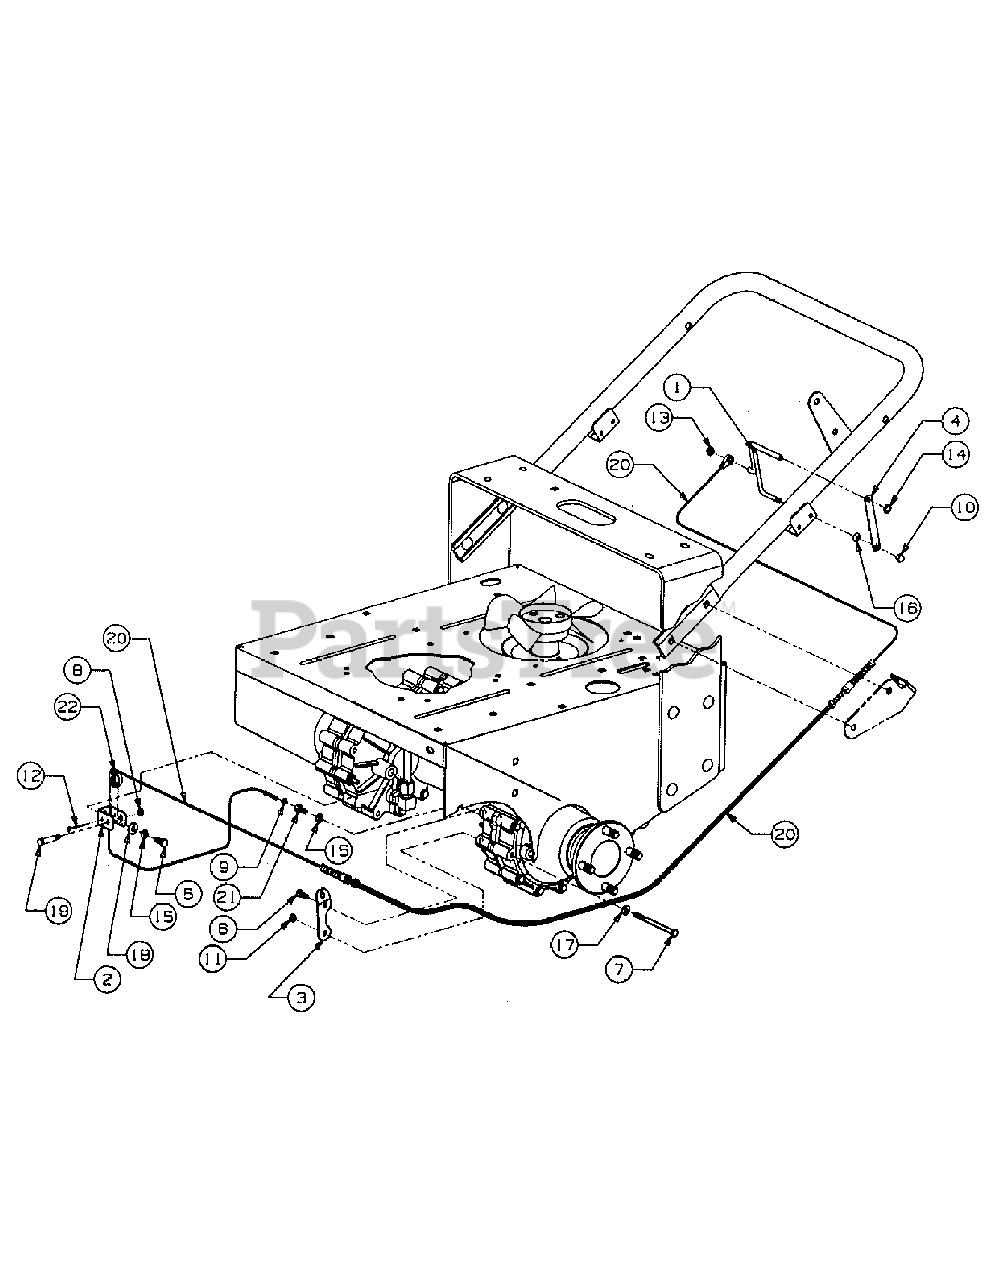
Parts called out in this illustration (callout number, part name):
1	Leverm Drive Wheel Release
2	Bracket, Pulley
3	Plate, Release Cable
4	Plate, Retainer
4	Graphic, Transaxle Release
5	Screw, Hex Cap, 5/16-24 x .75 Gr 5
6	Screw, Hex Wash Hd Tapp, 1/4-20 x .75
7	Screw, Hex Cap, 1/4-20 x 4.0
8	Nut, Hex Top Lock, 1/4-20
9	Nut, Hex #10-32
10	Nut, Hex Lock Stop, 1/4-28
11	Nut, Hex Top Lock, 1/4-20 Gr 5
12	Pin, Cotter, 5/32 Dia x 1.25
13	Nut, Cap Speed, .312 Stud
14	Nut, Push-On Speed, 5/16
15	Washer, Lock 5/16
16	Washer, Spring
17	Washer, Flat .25 x .62
18	Washer, Flat .312 x .750 x .119 Thk
19	Bolt, Pulley
20	Cable, Drive Wheel Release
21	Boltm Cable Adapter
22	Pulley, Cable
